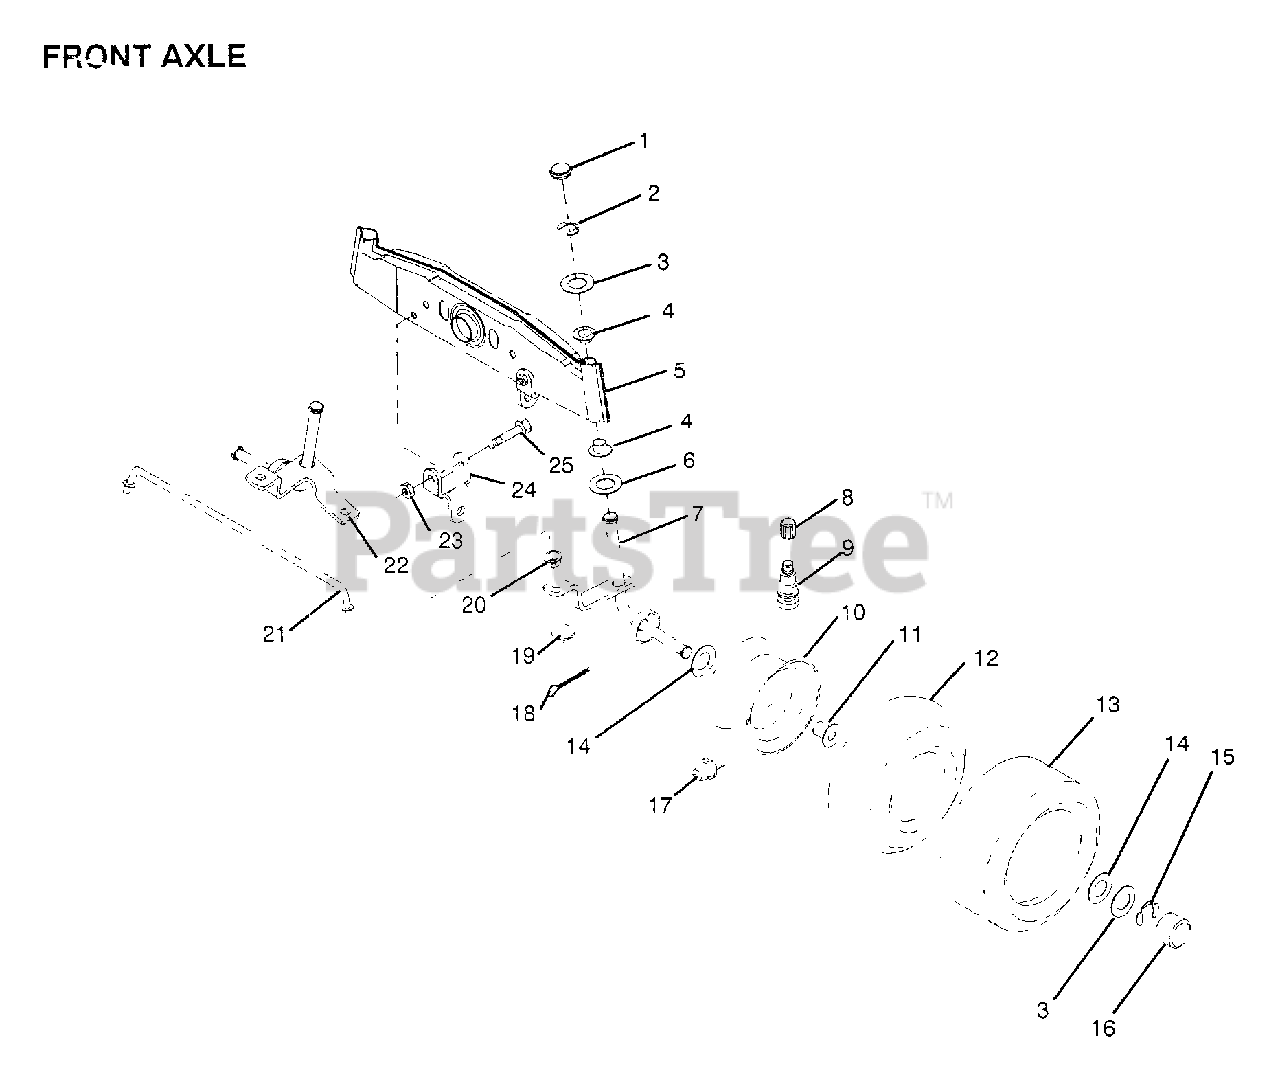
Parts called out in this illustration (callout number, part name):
1	CAP
2	RING
3	WASHER
4	NYLINER
5	AXLE FRONT
6	WASHER .T
7	SPINDLE RH
8	VALVE CAP
9	VALVE STEM LT
11	"FLANGE, BEARING"
12	TUBE.5.3/4.5/6
14	WASHER
15	RING
16	HUB CAP
17	FITTING LT
18	COTTER PIN
19	WASHER
20	BUSHING.DRAGLINK
21	ROD TIE
22	SPINDLE LH
24	"BRKT,FRONT STAB"
25	BOLT
